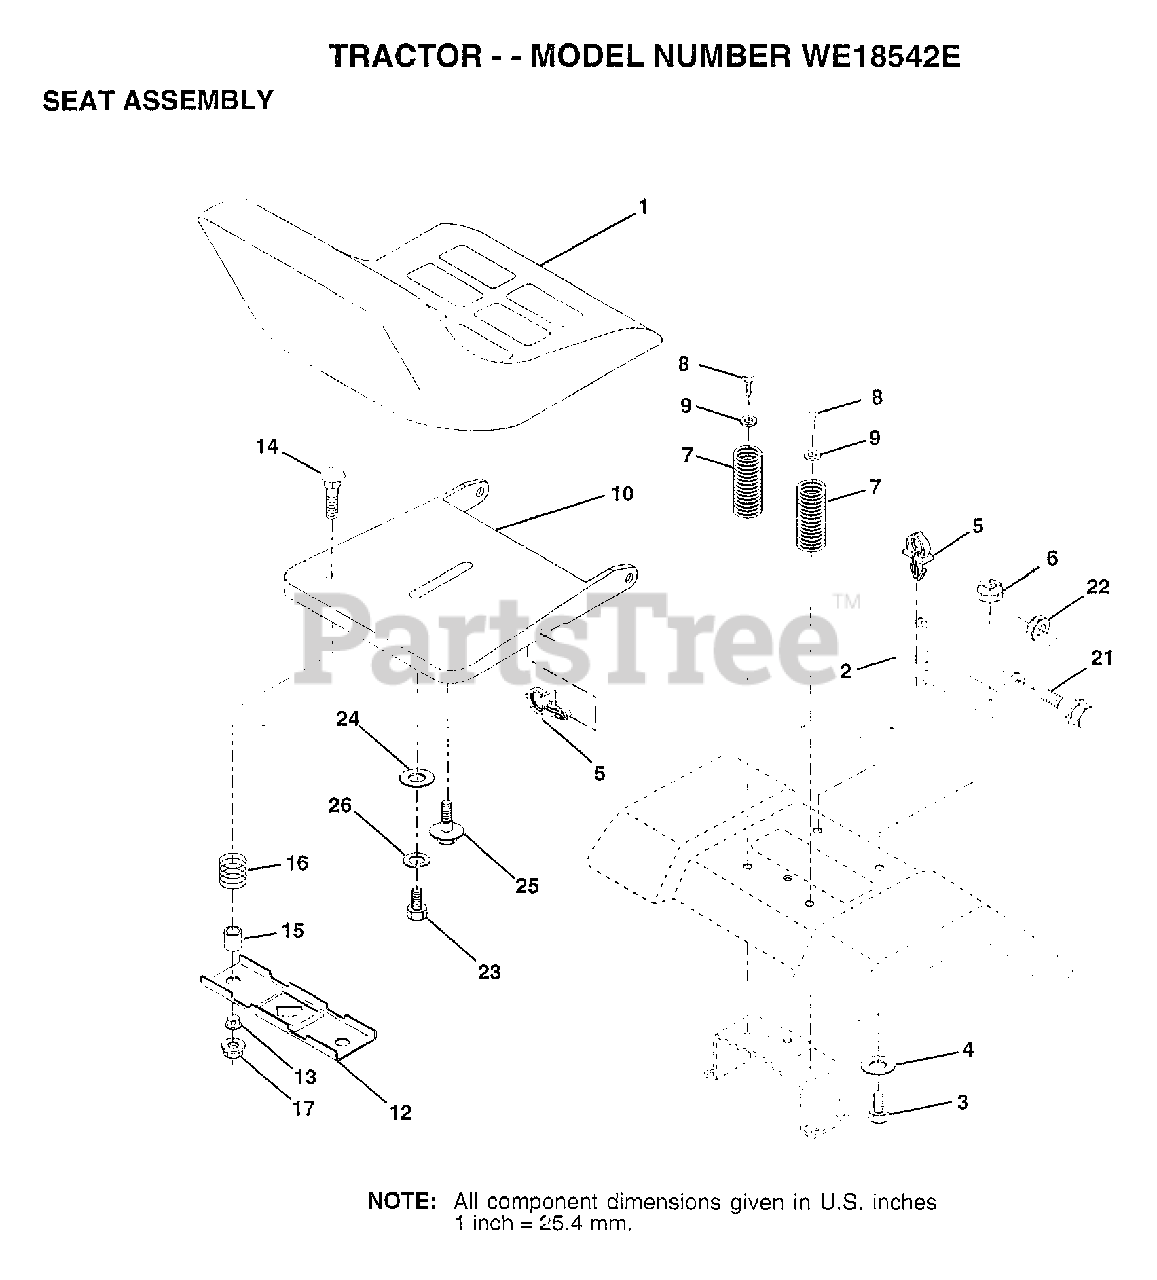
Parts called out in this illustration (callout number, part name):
2	BRACKET PVT SEAT
3	BOLT
4	WASHER PM
5	CLIP.PUSH-IN.HING
6	NUT
7	SPRING COMPRESSIO
8	SCREW GTV
9	WASHER
10	PAN-SEAT
12	BRKT SWITCH
13	BUSHING
14	BOLT-RD HD SQ NK
15	SPLIT SPACER
16	SPRING
21	"BOLT,SHOULDER"
22	NUT
23	BOLT
24	WASHER
25	"BOLT,SHOULDER"
26	LOCKWASHER
